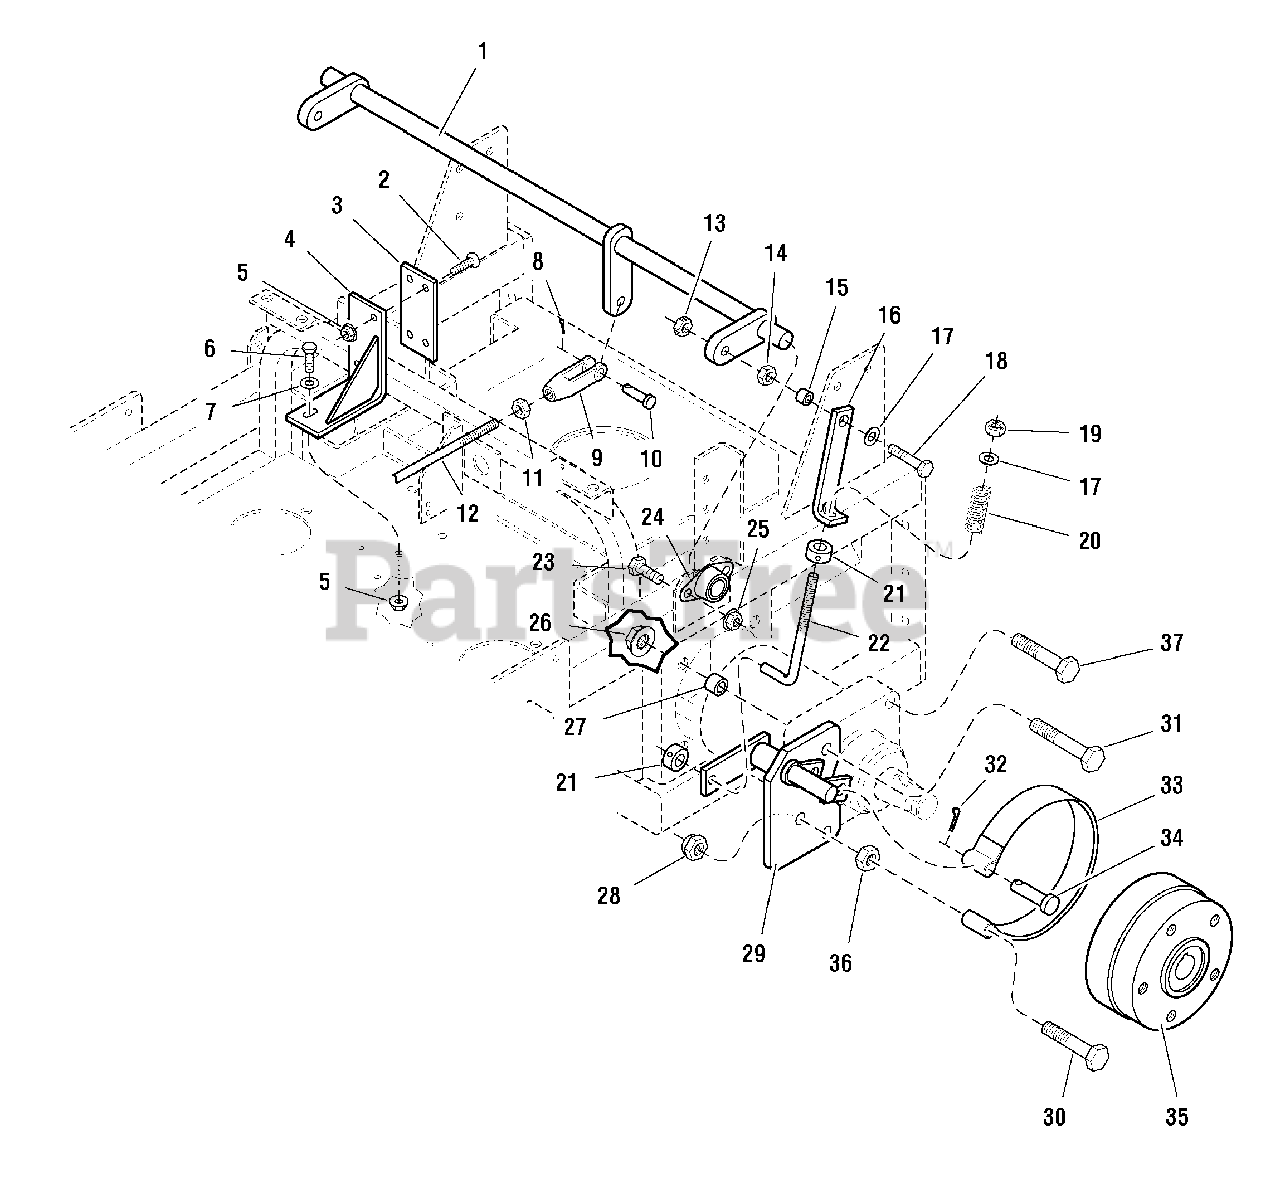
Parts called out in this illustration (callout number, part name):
1	BRAKE CROSS SHAFT
2	SCREW, 5/16-18 X 1, PHILLIPS HD, BZ
3	FRICTION PLATE
4	SUPPORT, Brake Shaft
5	NUT, Hex, Serrated Flange, 5/16-18
6	CAPSCREW, Hex Hd, 5/16-18 x 1
7	WASHER, 5/16
8	COTTER PIN
9	CLEVIS, 3/8-24
10	PIN, Clevis, 3/8 x 1
11	NUT, Hex, 3/8-24
12	BRAKE CONNECTING ROD
13	NUT, Hex, Side Lock, 3/8-16
14	NUT, Hex, 3/8-16
15	SPACER, .38 x .50 x .27
16	LINK, BRAKE LOCK - BLK
17	WASHER, 3/8
18	CAPSCREW, Hex Hd, 3/8-16 x 1-1/2
19	NUT, Hex, Top Lock, 3/8-16
20	BRAKE SPRING
21	COLLAR, Set, 3/8
22	ROD, Brake Adjustment
23	CAPSCREW, Hex Hd, 3/8-16 x 3/4
24	BEARING, Flange
25	NUT, Hex, Serrated Flange, 3/8-16
26	NUT, Hex Flange Lock, 1/2-20
27	SPACER, .51 x .75 x .56
28	NUT, Hex, Nylon Lock, 1/2-13
29	BRAKE BAND SHAFT-LH
30	CAPSCREW, Hex Hd, 1/2-13 x 3
31	CAPSCREW, Hex Hd, 1/2-20 x 3-1/2
34	PIN, Clevis, 1/2 x 2
36	NUT, Hex, 1/2-13
37	CAPSCREW, Hex Head, 1/2-20 x 3
